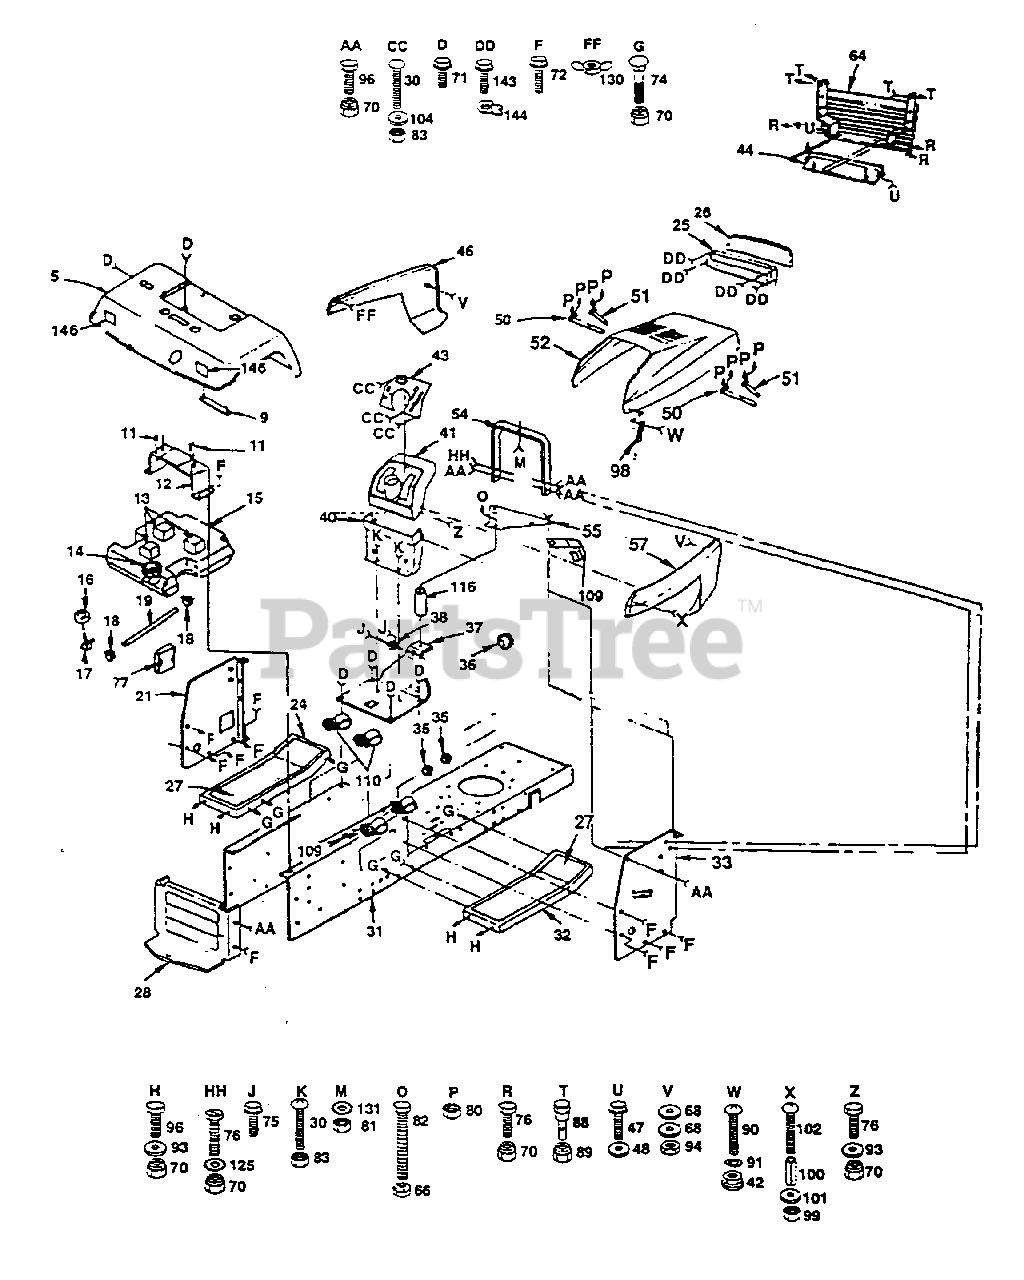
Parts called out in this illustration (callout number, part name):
5	Fender (AYP part number)
9	Strap, Fender (AYP part number)
11	Nut, Push (AYP part number)
12	Bracket, Fender (AYP part number)
13	Pad, Spacer (AYP part number)
14	Cap, Fuel (AYP part number)
15	Tank, Fuel (AYP part number)
16	Bushing (AYP part number)
17	Stem, Tank, Fuel (AYP part number)
18	Clamp, Hose (AYP part number)
19	Line, Fuel (AYP part number)
21	Panel, Dash, L.H. (AYP part number)
24	Footrest, L.H. (AYP part number)
25	Bezel, Assembly
26	Lens (AYP part number)
27	Pad, Footrest (AYP part number)
28	Drawbar (AYP part number)
29	Washer, 11/32 X 3/4 X 12 Ga. (AYP part number)
30	Screw, Cr. Thd. 5/16-18 x 3/4 (AYP part number)
31	Chassis (AYP part number)
32	Footrest, R.H. (AYP part number)
33	Panel, Dash, R.H. (AYP part number)
35	Grommet, Split (AYP part number)
36	Grommet (AYP part number)
37	Saddle (AYP part number)
38	Bushing, Steering (AYP part number)
40	Dash Assembly, Lower (AYP part number)
41	Dash (AYP part number)
42	Nut, Weld (AYP part number)
43	Plate, Dash (AYP part number)
44	Strap, Grill (AYP part number)
46	Panel, Side, L.H. (AYP part number)
47	Screw, Hex Wsh. Thd. Cut 1/4-20 X 3/4 (AYP part number)
48	Washer 9/32 X 5/8 X 16 Ga. (AYP part number)
49	Screw, Hex Wsh Thdrol 5/16-18 X 3/4
50	Strap Assembly, Hinge, Rear (AYP part number)
51	Strap Assembly, Hinge, Front (AYP part number)
52	Hood (AYP part number)
54	Support, Dash (AYP part number)
55	Plate, Support, Battery (AYP part number)
57	Panel, Side R.H. (AYP part number)
64	Grill Assembly (AYP part number)
65	Bolt, Shoulder 5/16-18 (AYP part number)
66	Nut, Lock 5/16-18
68	Washer 9/32 X 3/4 X 16 Ga. (AYP part number)
70	Nut, Crownlock 3/8-16
71	Screw, Hex Washer Thread Rolling 3/8-16 x 1/2 (AYP part number)
72	Screw, Hex Washer Thread Rolling 3/8-16 x 3/4 (AYP part number)
74	Bolt, Carriage 3/8-16 x 3/4 (AYP part number)
75	Screw, Hex Self Tapping #10-16 x 1/2 (AYP part number)
76	Bolt, Hex 3/8-16 x 1 (AYP part number)
77	Cover, Access (AYP part number)
80	Nut, Hex Keps (AYP part number)
81	Nut, Hex 1/4-20 (AYP part number)
82	Bolt, Hex 5/16-18 x 2 (AYP part number)
83	Nut, Keps 5/16-18 (AYP part number)
88	Bolt, Shoulder 1/4-20 (AYP part number)
89	Crownlock Nut 1/4-20 (AYP part number)
90	Screw, Pan Hd. Mach. #10-24 1/2 (AYP part number)
91	Washer, Lock #10 (AYP part number)
93	Washer 13/32 x 13/16 x 12 Ga. (AYP part number)
94	Nut, Fin Hex 1/4-20 UNC (AYP part number)
96	Bolt, Hex 3/8-16 x 3/4 (AYP part number)
98	Latch, Hood (AYP part number)
99	Nut, Keps 10-24 (AYP part number)
100	Spacer, Split 10 x 3/4 (AYP part number)
101	Washer 7/32 x 1/2 x 18 Ga. (AYP part number)
102	Screw, Mach. Cr. Pan 10-24 x 1-1/4 (AYP part number)
104	Washer 11/32 x 11/16 x 16 Ga. (AYP part number)
109	Clip (AYP part number)
110	Insulated Clip (AYP part number)
116	Spacer (AYP part number)
123	Adjustment Knob (AYP part number)
124	Washer 17/32 x 1-3/16 x 12 Ga. (AYP part number)
125	Washer Lock 3/8 Ext. Tooth (AYP part number)
126	Washer 13/32 x 1 x 14 Ga. (AYP part number)
130	Wing Nut (AYP part number)
131	Washer, 1/4 Ext. Tooth (AYP part number)
140	Spring. Compression (AYP part number)
141	Screw, Pan Hd. #10-32 (AYP part number)
142	Nut, Keps #10 (AYP part number)
143	Screw, Hex WH HD Tap #10-16 X 5/8 (AYP part number)
144	"J" Fastener (AYP part number)
147	Bolt, Shoulder 5/16-18 x .62 (AYP part number)
